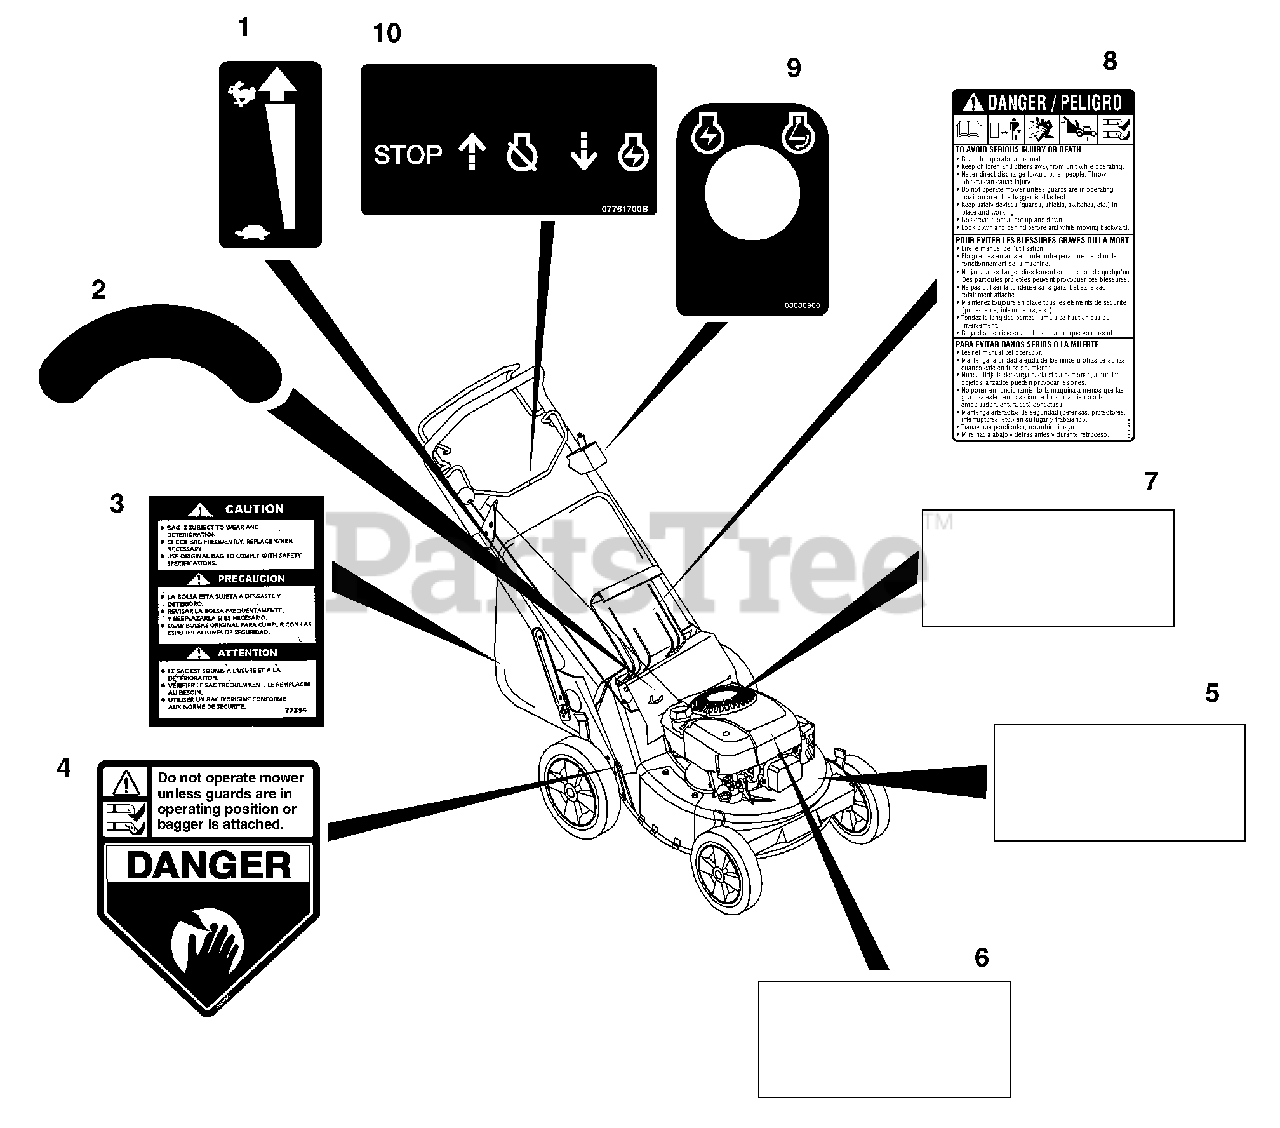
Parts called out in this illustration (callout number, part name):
1	Decal, Speed Control
2	Decal, Swoosh Husqvarna
3	Label, Bagger 21"
4	Decal, Danger
5	Decal, 580 R
5	Decal, 580 RS
5	Decal, 580 RSE
5	Decal, 580 RSW
5	Decal, 580 BBC
5	Decal, 600 C
6	Decal, Husqvarna & Robin
6	Decal, Husqvarna-Briggs & Stratton Intek OHV
7	Decal, Robin 6HP OHV-Commercial
7	Decal, OHV 6.5 Husqvarna
8	Decal, Bilingual Danger
9	Decal, Key Switch
10	Decal, Engine Control
